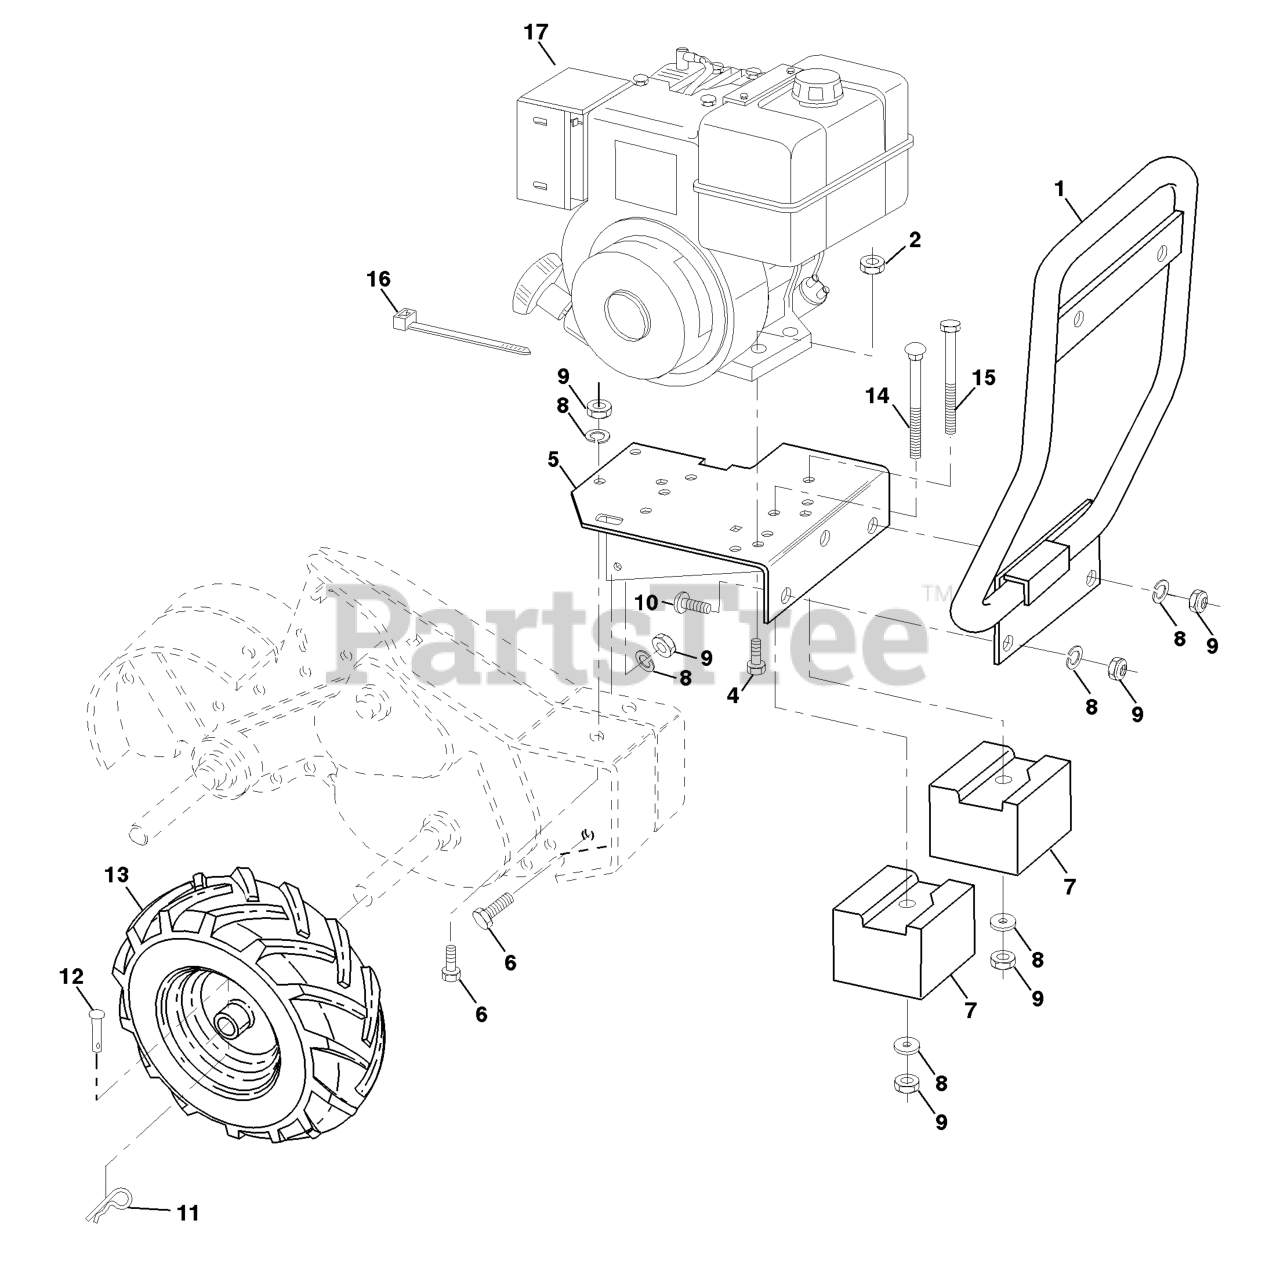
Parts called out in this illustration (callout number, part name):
2	NUT
4	BOLT, HEX 5/16-18X1-3/4
5	ENGINE BRACKET
6	BOLT
7	COUNTER WEIGHT RH
8	WASHER, LOCK 3/8
9	NUT.HEX.3/8-16UNC
10	BOLT D
11	SPRING TI
13	TIRE.16X4-8.CHEVRON.TILLER
13	RIM
13	VALVE STEM LT
14	Bolt, Carriage 3/8-16 x 4-1/2
15	BOLT, HEX 3/8-16X4-1/2
17	Starter Kit B & S
